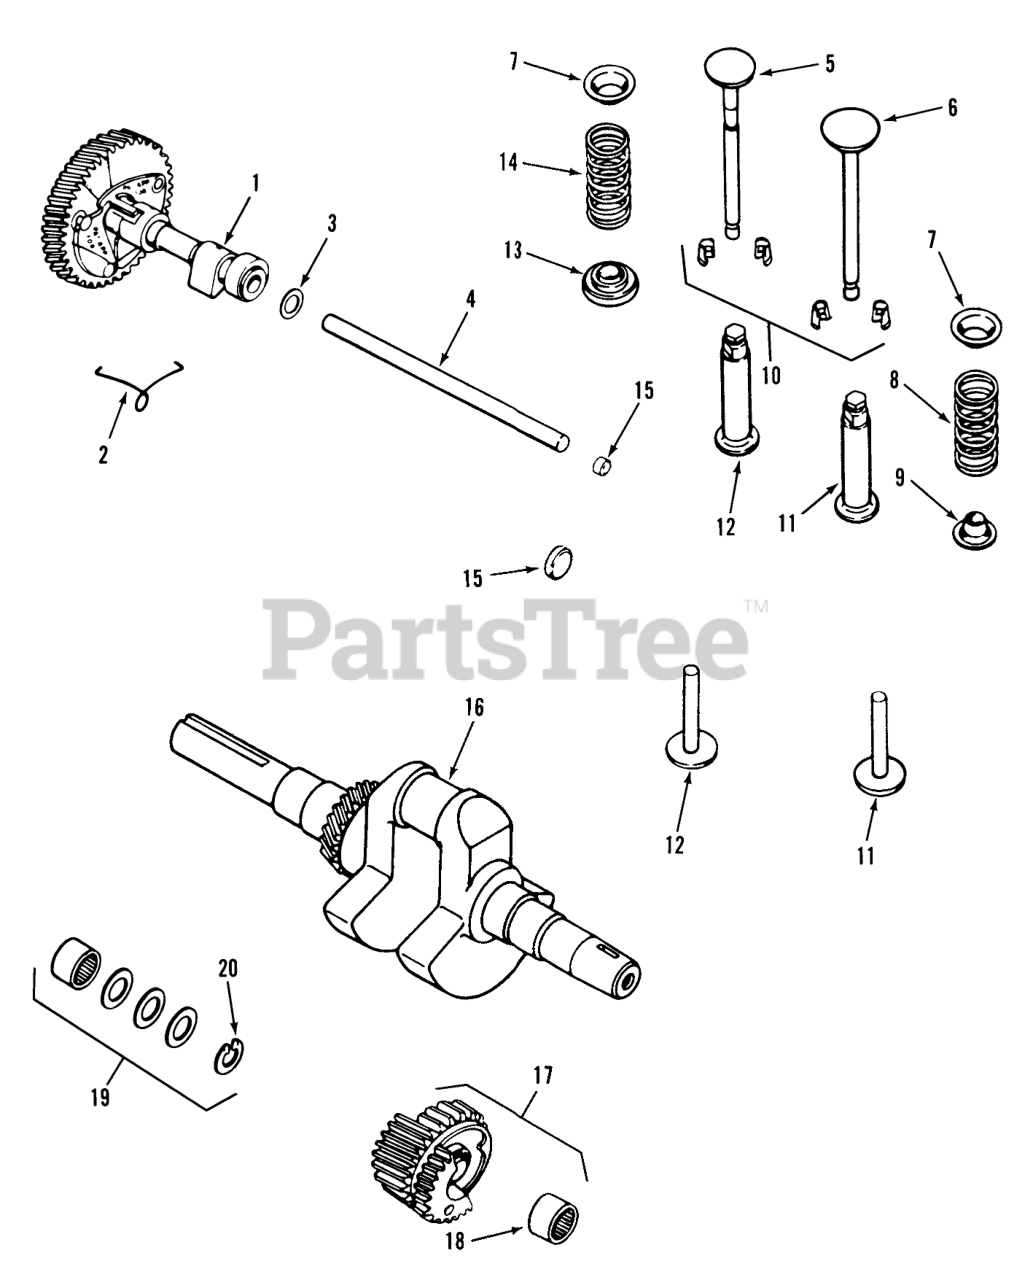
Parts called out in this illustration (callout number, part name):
1	Camshaft Assy (includes item 2) 308 Only
2	Spring
3	Camshaft Spacer .005 308 Only
4	Camshaft Pin 308 Only
5	Exhaust Valve 308 Only
6	Intake Valve 308 Only
7	UpperSpring Retainer
8	Intake Valve Spring 308
9	Retainer-Spring
10	Kit-Retainer
11	Intake Valve Tappet 308 Only
12	Exhaust Valve Tappet 308 Only
13	Exhaust Valve Rotator 308 Only
14	Exhaust Valve Spring 308 Only
15	Cup Plug 7/16 308 Only
16	Crankshaft 3-3/4 x 1 tapped PTO 308 Only
17	Gear Assy (includes item 18) 312, 414, 416
18	Bearing-Needle
19	Spacer Kit (includes item 20) 312, 414, 416
20	Retainer
